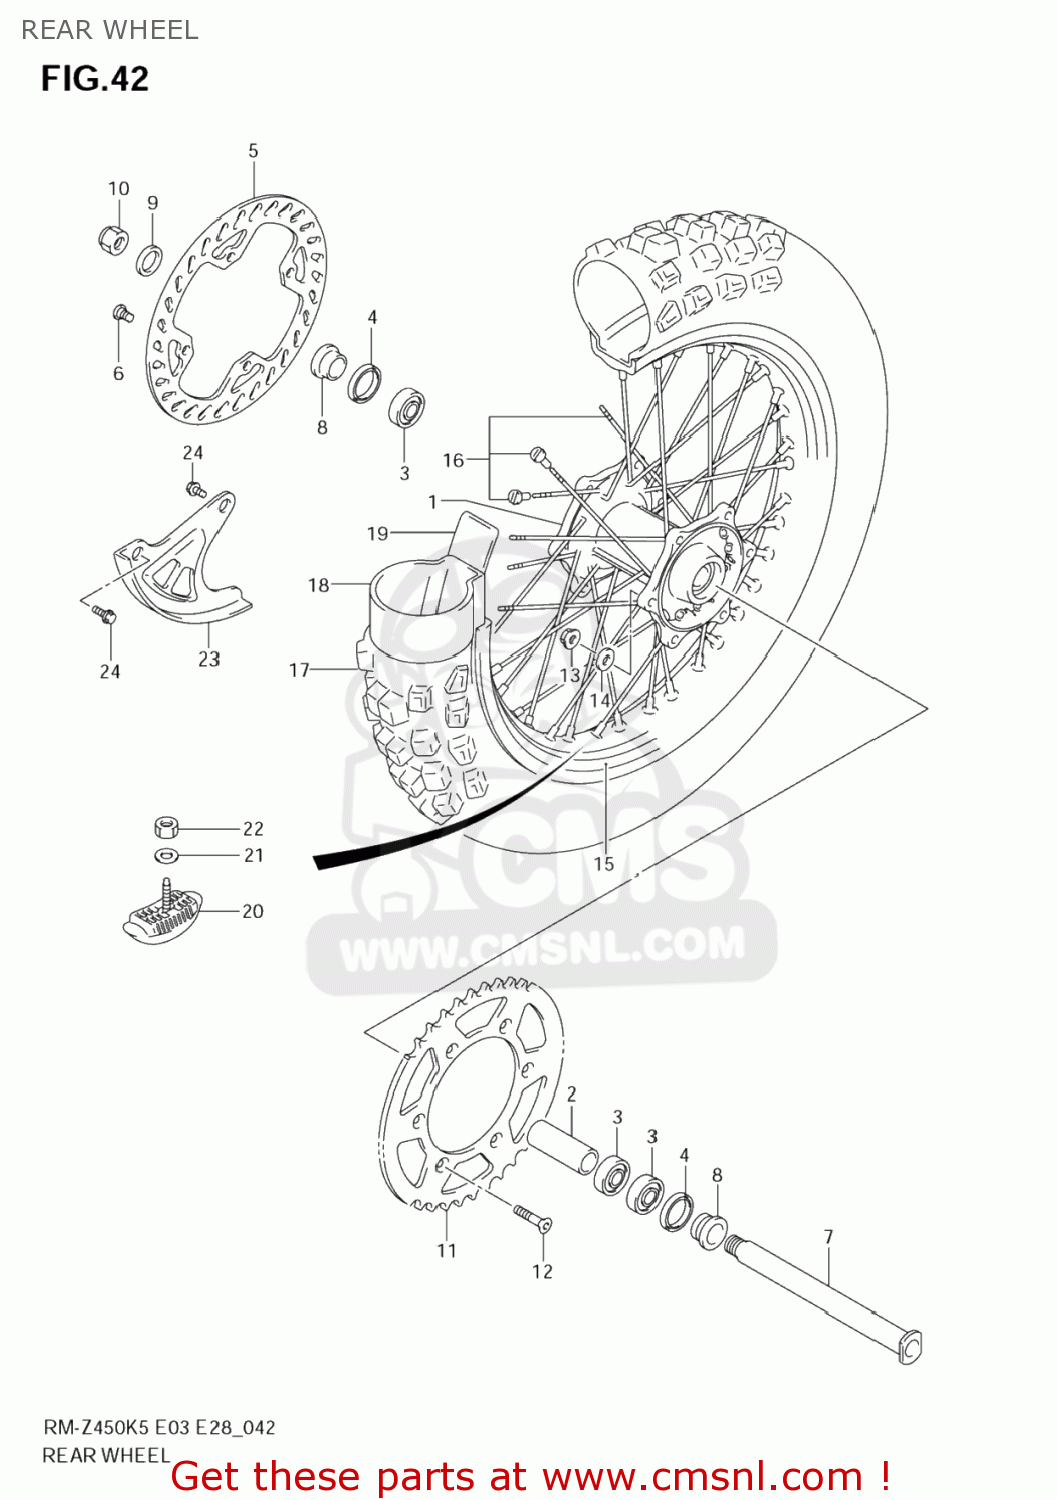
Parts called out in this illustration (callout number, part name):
1	HUB,RR
2	SPACER,REAR HU
3	BEARING(25X42X9)
4	SEAL,OIL(32X43X7)
5	DISC,RR BRAKE
6	SCREW(8X15)
7	AXLE,REAR
8	SPACER,REAR AX
9	WASHER(22X35X2)
10	NUT
11	SPROCKET,RR(NT:49)
12	BOLT(8X28)
13	NUT
14	WASHER
15	RIM,RR WHEEL(19X2.15 AL)(WHT)
16	SPOKE SET,RR WHEEL
17	TIRE COMP,RR(1
18	TUBE ASSY,WHEEL INNER
19	PROTECTOR,WHEE
20	STOPPER,BEAD(2.15)
21	WASHER
22	NUT
23	COVER,REAR DIS
24	BOLT(6X12)
